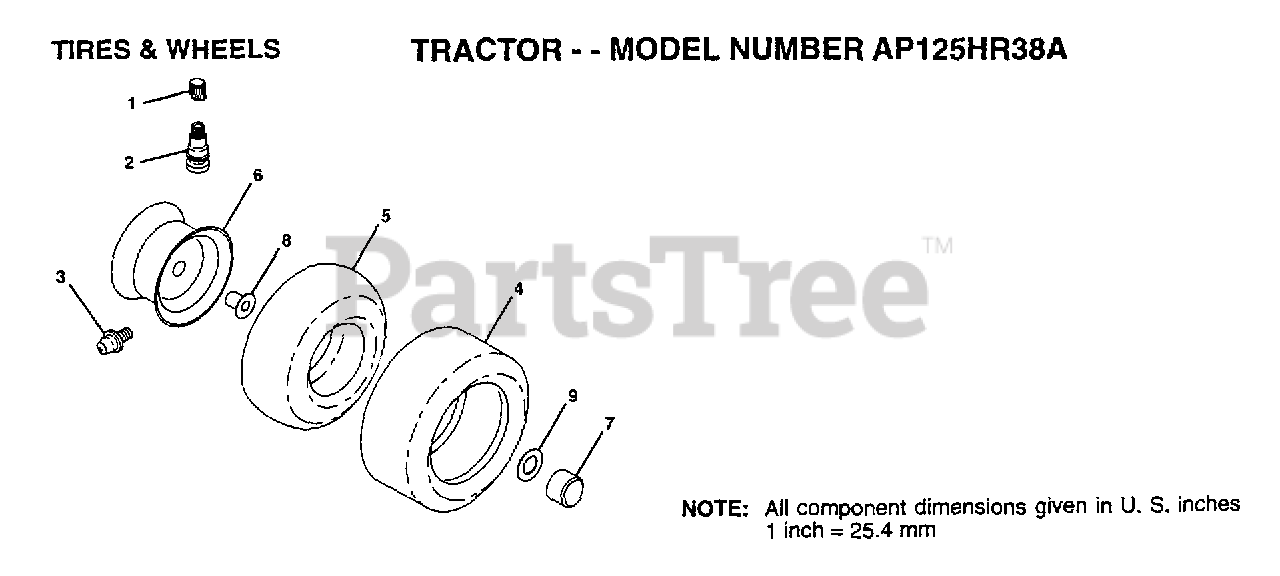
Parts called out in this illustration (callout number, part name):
1	VALVE CAP
2	VALVE STEM LT
3	FITTING LT
5	TUBE.5.3/4.5/6
6	"RIM.6"".FRONT.GREY"
7	HUB CAP
8	"FLANGE, BEARING"
9	WASHER
